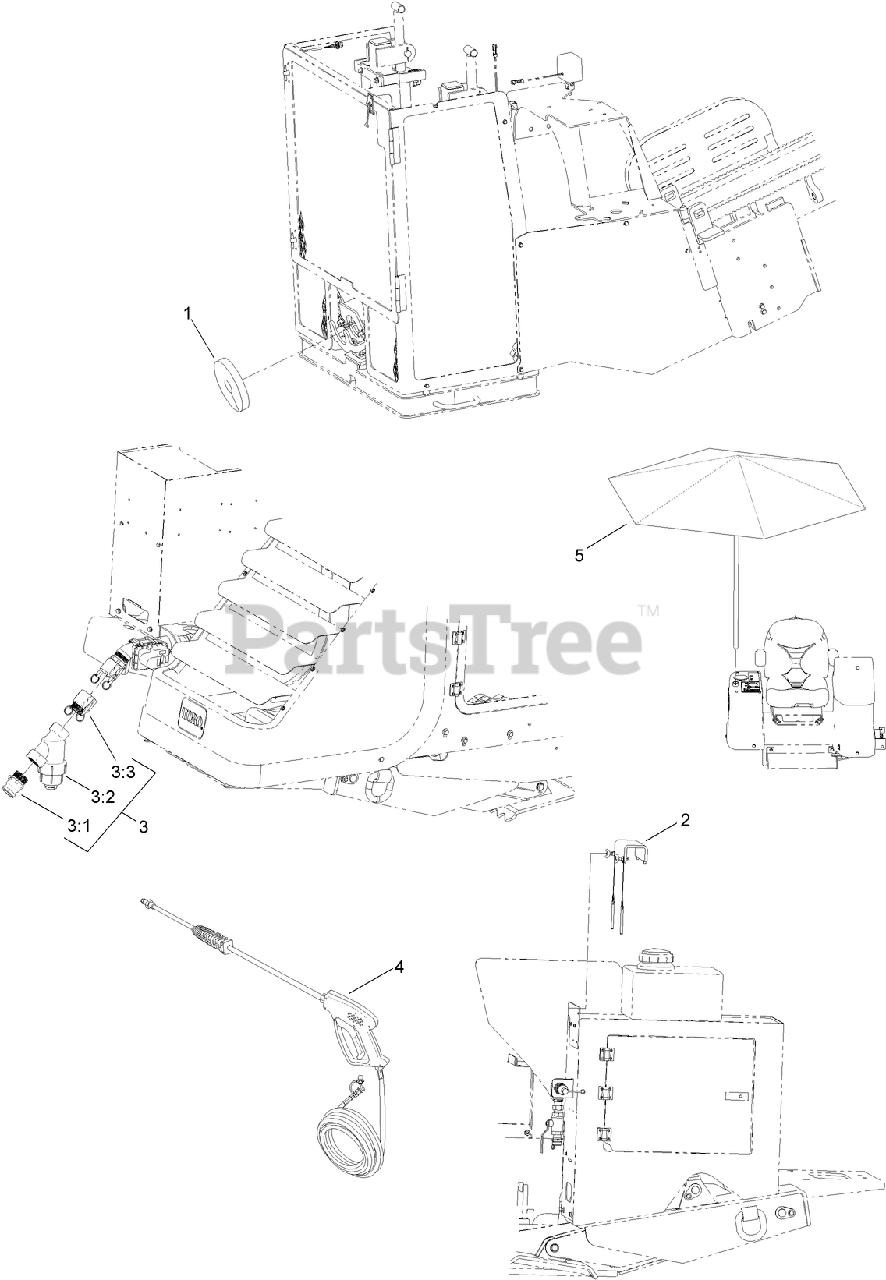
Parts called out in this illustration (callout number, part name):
1	WIPER-SPLIT
2	CYLINDER LOCKOUT ASM
3	STRAINER KIT
3:1	ADAPTER-MALE
3:2	STRAINER-Y
3:3	FITTING-CAMLOK
4	WASH DOWN WAND ASM
5	UMBRELLA-TORO
